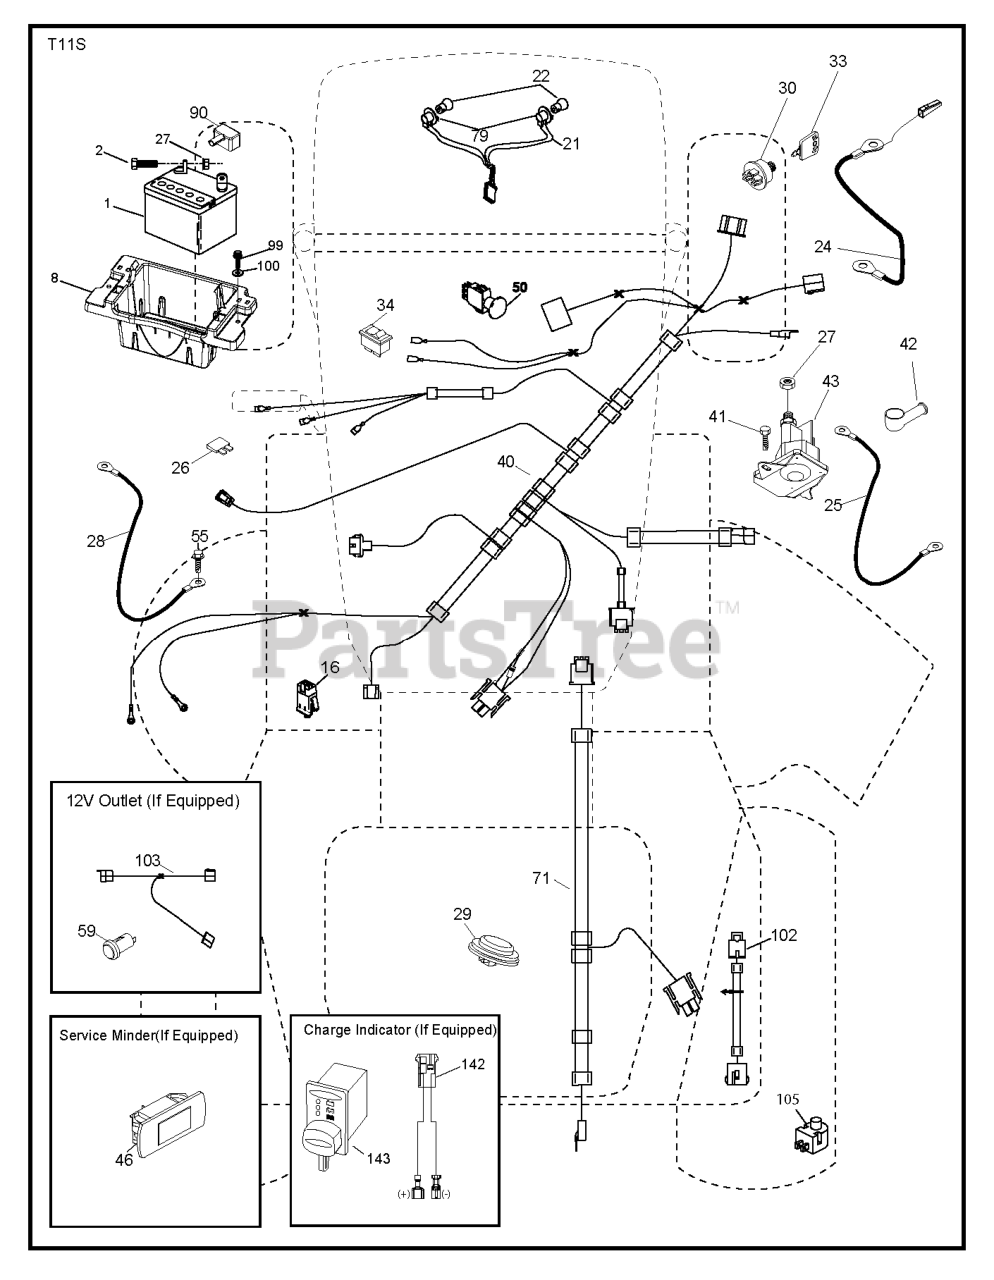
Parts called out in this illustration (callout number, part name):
1	Battery 12 Volt 25 Amp
2	BOLT.HEX.1/4.X.3/4.DICHROMATE
8	TRAY.BATTERY BOX.FRONT
16	SWITCH INTERLOOK PUSH-IN
21	HARNESS.LIGHT W/4152J BULBS
24	CABLE.FRBATT.W/WIRE.8GA.8
25	CABLE.STARTER.8GA.17.5
26	FUSE 20AMP
27	NUT
28	CABLE.GROUND.21"BLK.8GA.90T
29	SWITCH.SEAT.DELTA.OPC.
30	SWITCH.IGN.DELTA.W.LGH.ROS
33	KEY.CHAIN.BLISTER.PACK.GEN.INT
40	HARNESS-CHASSIS SUB
41	SCREW
42	TERMINAL COVER
43	SOLENOID.STARTER.BRASS.PLUNGER
46	GUAGE.SRVCMNDR.HRMTR.
50	SWITCH.PTO.8TERMINAL.STD.BLK
55	SCREW 5/16"
71	HARNESS.IGN.DASH.HUSQ/PRED
79	BULB HOLDER ASM.
90	COVER.TERMINAL.BATTERY
99	SCREW HEXWSHR 1/4-20X3/4
102	REVERSE SWITCH
105	HARNESS PIGTAIL PCH TEX ROS
142	CHARGE.PORT.PIGTAIL HARNESS
143	CHARGE.PORT
